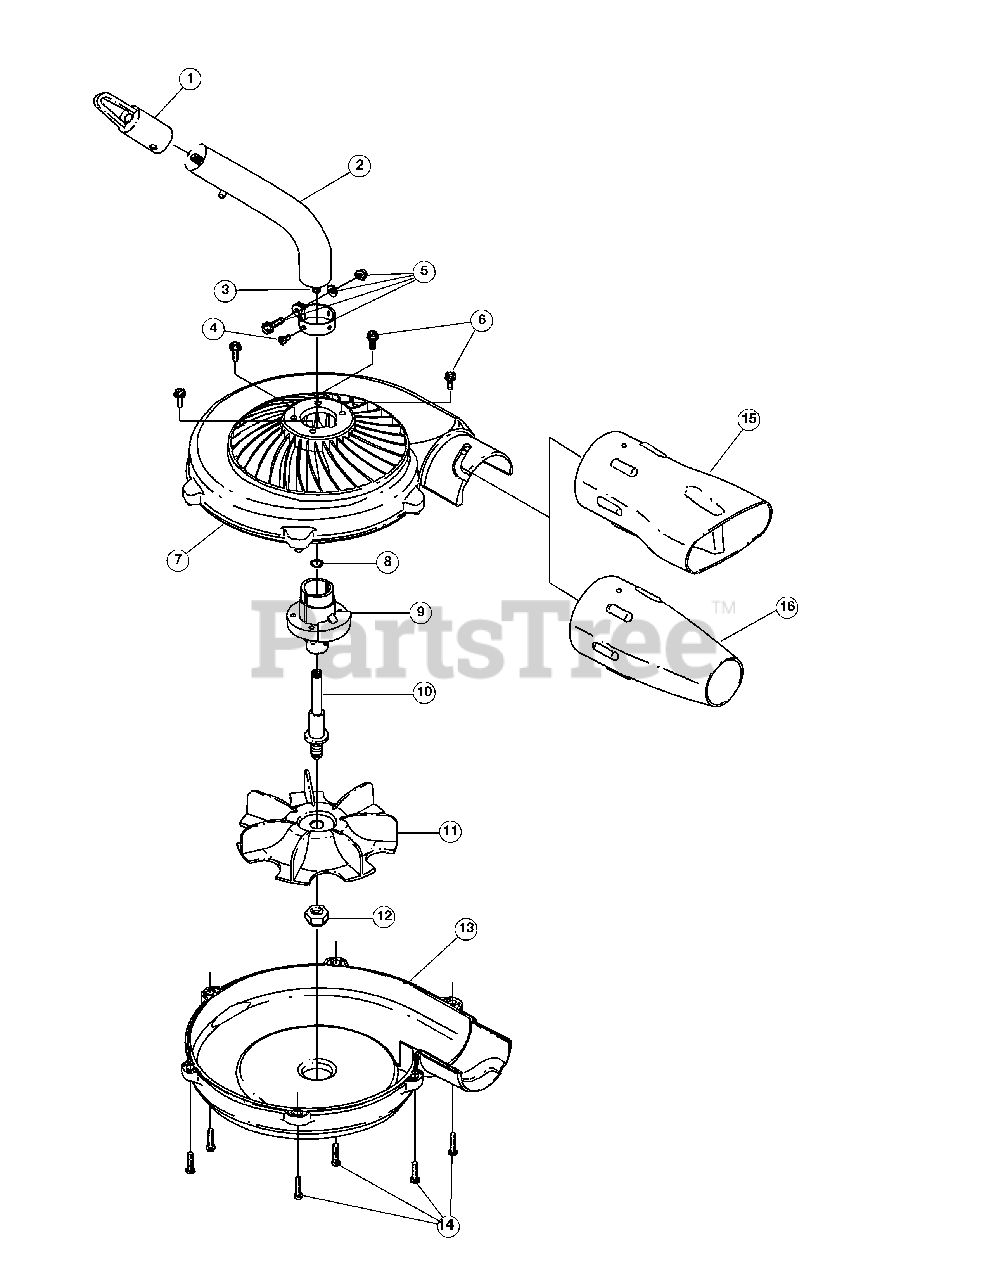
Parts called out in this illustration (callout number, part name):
1	Hanger
2	Drive Shaft Housing Assembly
3	Drive Shaft Assembly
4	Anti-Rotation Screw
5	Lower Clamp Assembly (includes 4)
6	Mounting Screw
7	Upper Housing
8	Palnut
9	Bushing Assembly Housing
10	Shaft Impeller
12	Nut and Washer
13	Lower Housing
14	Mounting Screw
15	Flare Nozzle
16	Concentrator Nozzle
